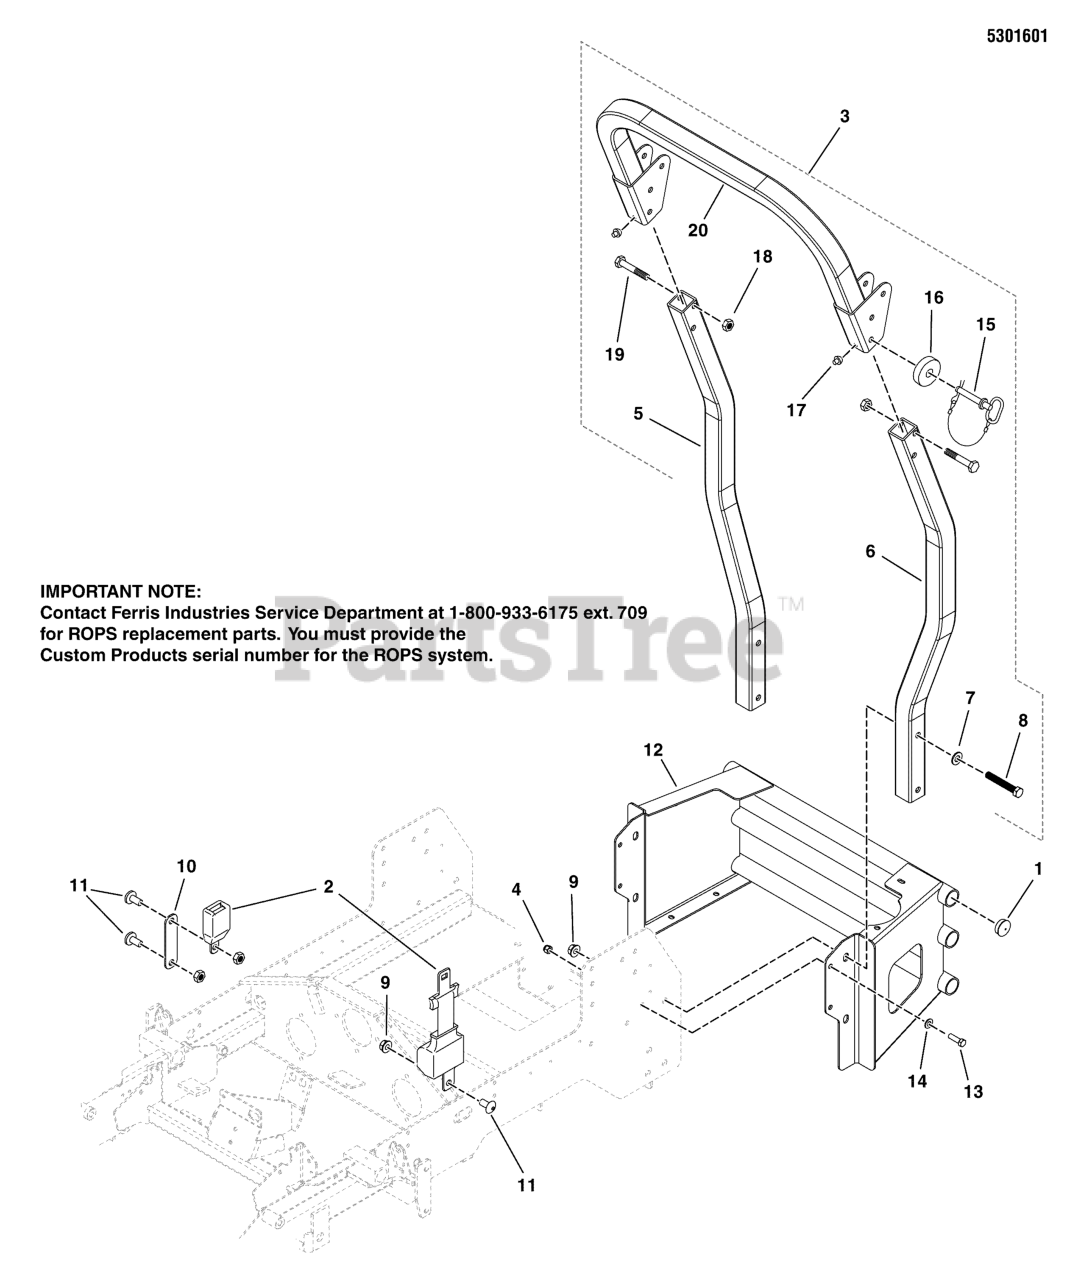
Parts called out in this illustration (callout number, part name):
1	PLUG, PANEL, 1.25 - BLACK
2	SEAT BELT, RETRACTING - ASSM
3	ROPS (Call 1-800-933-6175 ext. 2193 if replacing a ROPS)
4	NUT, 3/8-16 HEX NYLOCK FLANGE
5	ROLL BAR POST, RH
6	ROLL BAR POST, LH
7	WASHER, 1/2 SAE
8	BOLT, 1/2-13 X 3-1/4, HEX HD, GD5, CZ (SV)
9	NUT, Hex Flange, Nylock, 1/2-13
10	EXTENSION, SEAT BELT - BLK
11	SCREW, 1/2-13 X 1.00, SHCS
12	BUMPER, REAR, IS2500
13	BOLT, 3/8-16 X 1" GD5 CZ
14	WASHER, 3/8 SAE
15	PIN, HINGE W/ LANYARD
16	WASHER, EPDM FOAM, 1/2" ID
17	BUMPER, ROPS
18	NUT
19	BOLT
20	ROLL BAR TOP LOOP
